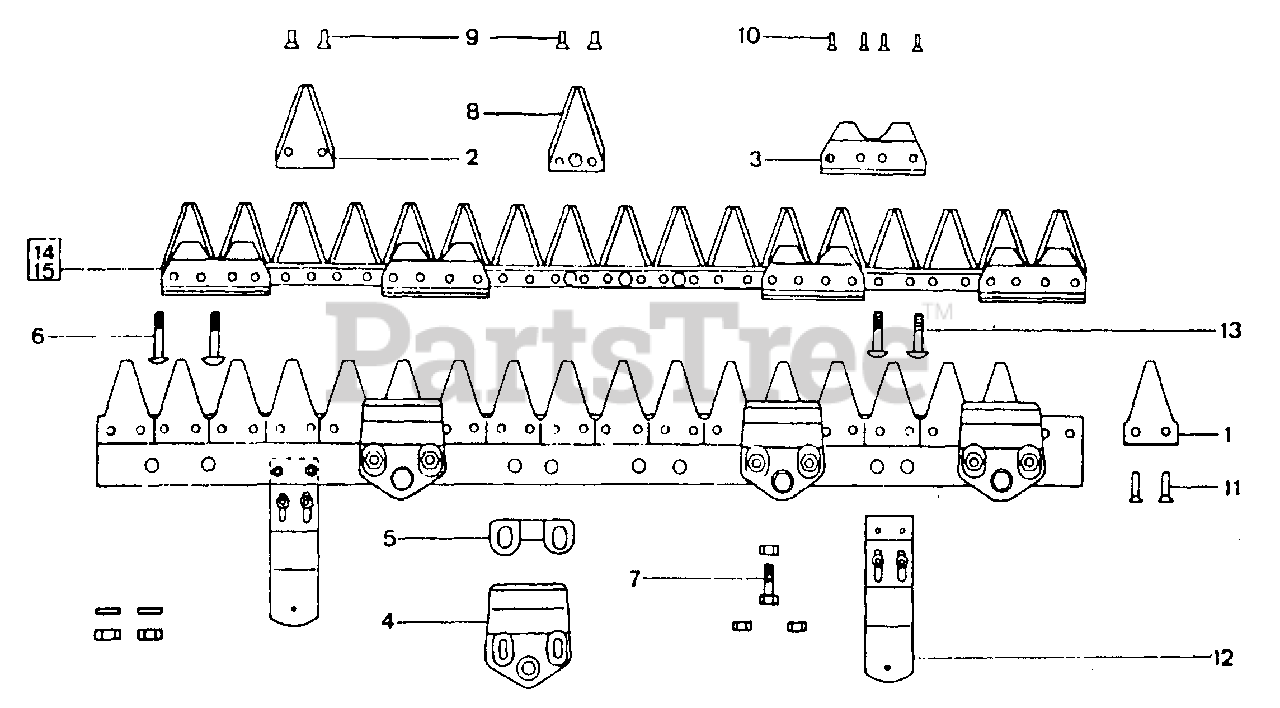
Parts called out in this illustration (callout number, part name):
1	Blade Section
2	Blade Section - 2 Holes
4	Blade Guide
6	Bolt M8 x 40 & Nut
7	Bolt HM8 x 30 & Nylstop Nut
8	Blade Sections - 3 Holes
9	Rivets CS90 5.3 x 14
10	Rivets CS90 5.3 x 16
12	Height Adjusters
13	Bolt M8 x 25 & Washer
15	Complete Cutter Blade Assembly
